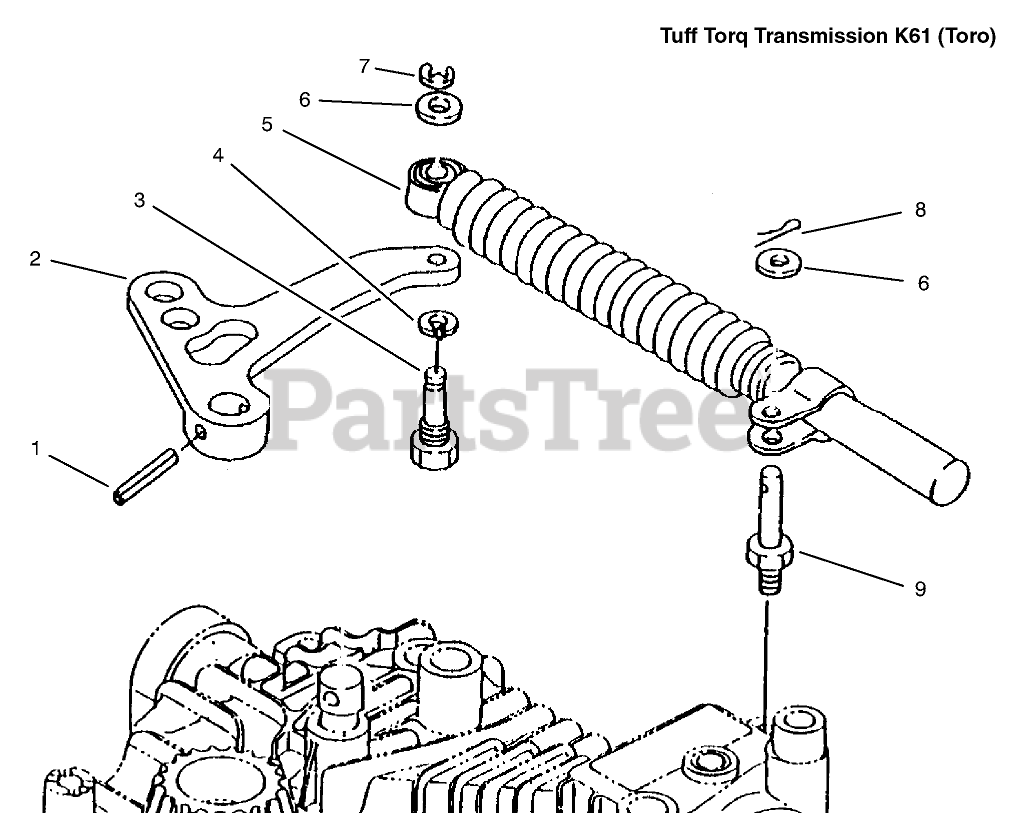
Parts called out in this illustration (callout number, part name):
1	PIN-ROLL
3	BOLT-KIT
4	WASHER
5	SHOCK ABSORBER KIT
6	WASHER
8	PIN-COTTER
9	STUD-KIT
